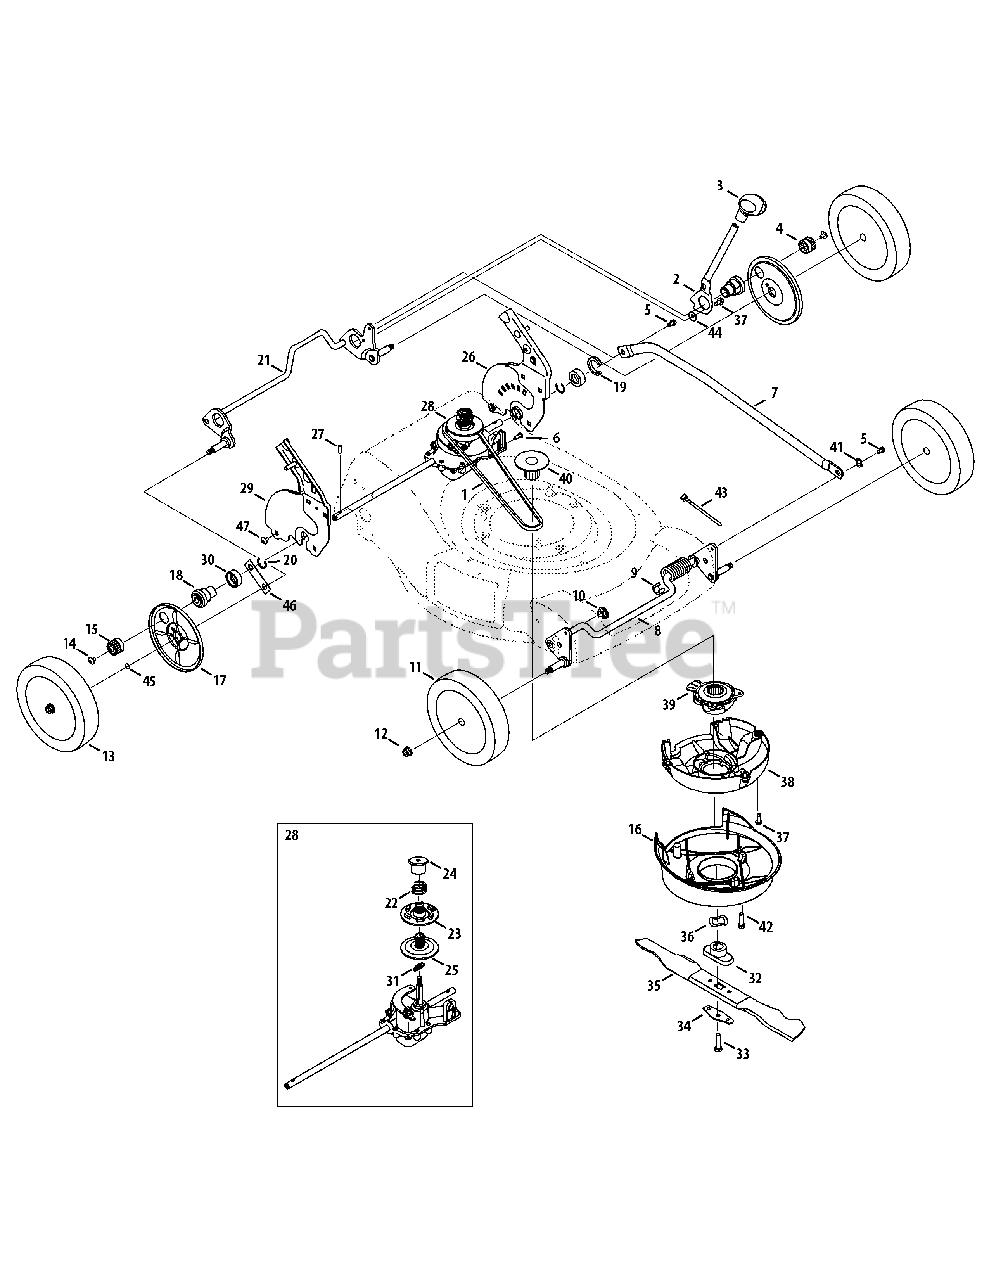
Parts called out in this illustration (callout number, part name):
1	V-Belt
3	Foam Grip - Black
4	Spur Gear 14T LH
5	Shoulder Screw 1/4-20 x .50
6	Screw, #12-16
8	Front Bracket Assembly
10	Split Hex Flange Bearing
11	Fr. Wheel 8 x 2.125 Grey Idle S-Wave
12	Hex L-FlangeNut 3/8-16 Gr. F, Nylon
13	Rear Wheel Ass'y 8" TVS S-Wave Grey
14	Pan Scr. 1/4-20 x .390
15	Spur Gear 14T RH
17	Wheel Dust Cover
18	Transmission Bearing Support
20	Retaining Ring .875
21	Rear Bracket Assembly
22	Compression Spring
23	Upper Pulley
26	Handle Bracket Ass'y LH
28	Transmission Assembly
29	Handle Bracket Ass'y LH
30	Bearing Support Spacer
31	Extension spring
32	Blade Adapter
33	Screw, 3/8-24 x 1.50
34	Blade Bell Support
35	21" Mulching Blade
36	Space Washer
37	Hex Wash S-Tapp Scr 1/4-20 x .50
38	Engine Baffle
39	Lower Pulley Assembly
42	Screw 1/4-15 x 1.250
44	Cupped Washer .340 x .872 x .080
45	Ring, .375 ID x .054
46	Gear Retiner Strap
